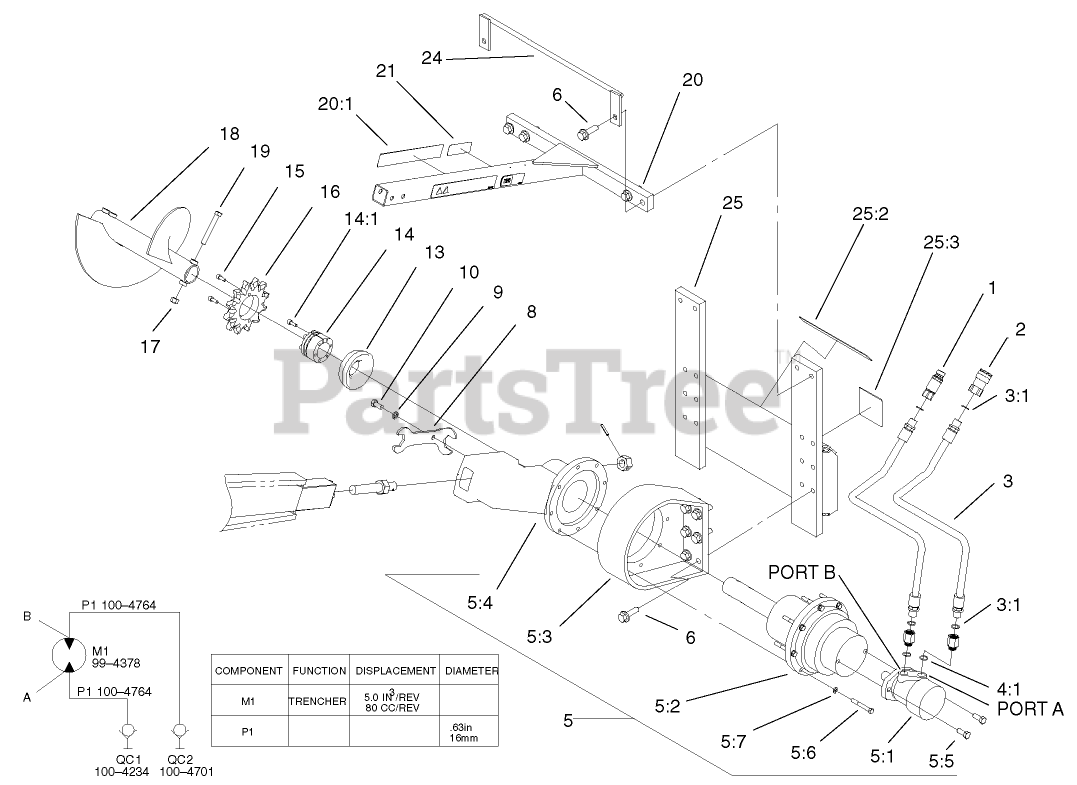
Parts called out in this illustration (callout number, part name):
1	NIPPLE-CONNECT, PRESSURE
2	COUPLER-FACE, FLUSH
3	HOSE-HYDRAULIC
3:1	O-RING
4	ADAPTER-CONVERSION
4:1	O-RING
5	Trencher Drive ASM
5:1	MOTOR-HYD, 80CC (1 INCH SHAFT)
5:1	MOTOR-HYD(OPTIONAL), 100CC-1 INCH SHAFT
5:1	MOTOR-HYD(OPTIONAL), 80CC-32MM SHAFT
5:1	MOTOR-HYD(OPTIONAL), 100CC-32MM SHAFT
5:2	GEARBOX ASM
5:3	MOUNT-DRIVE, PLANETARY
5:4	MOUNT-BOOM
5:5	SCREW-HH, LH
5:6	SCREW-HH
5:7	WASHER-LOCK
8	SPANNER
9	WASHER-LOCK
10	SCREW-HH
13	PROTECTOR-SEAL
14	LOCK-TAPER
14:1	SCREW-HSH
15	SCREW-HSH
16	SAND SPROCKET-12T
17	NUT-LOCK, NI
18	AUGER ASM,
19	SCREW-HH
20	SAFETY RAIL ASM
20:1	DECAL-DANGER
21	DECAL-ATTACHMENT, DINGO
24	Hose Guide ASM
25	MOUNTING ASM
25:2	DECAL-DANGER
25:3	DECAL-DANGER
